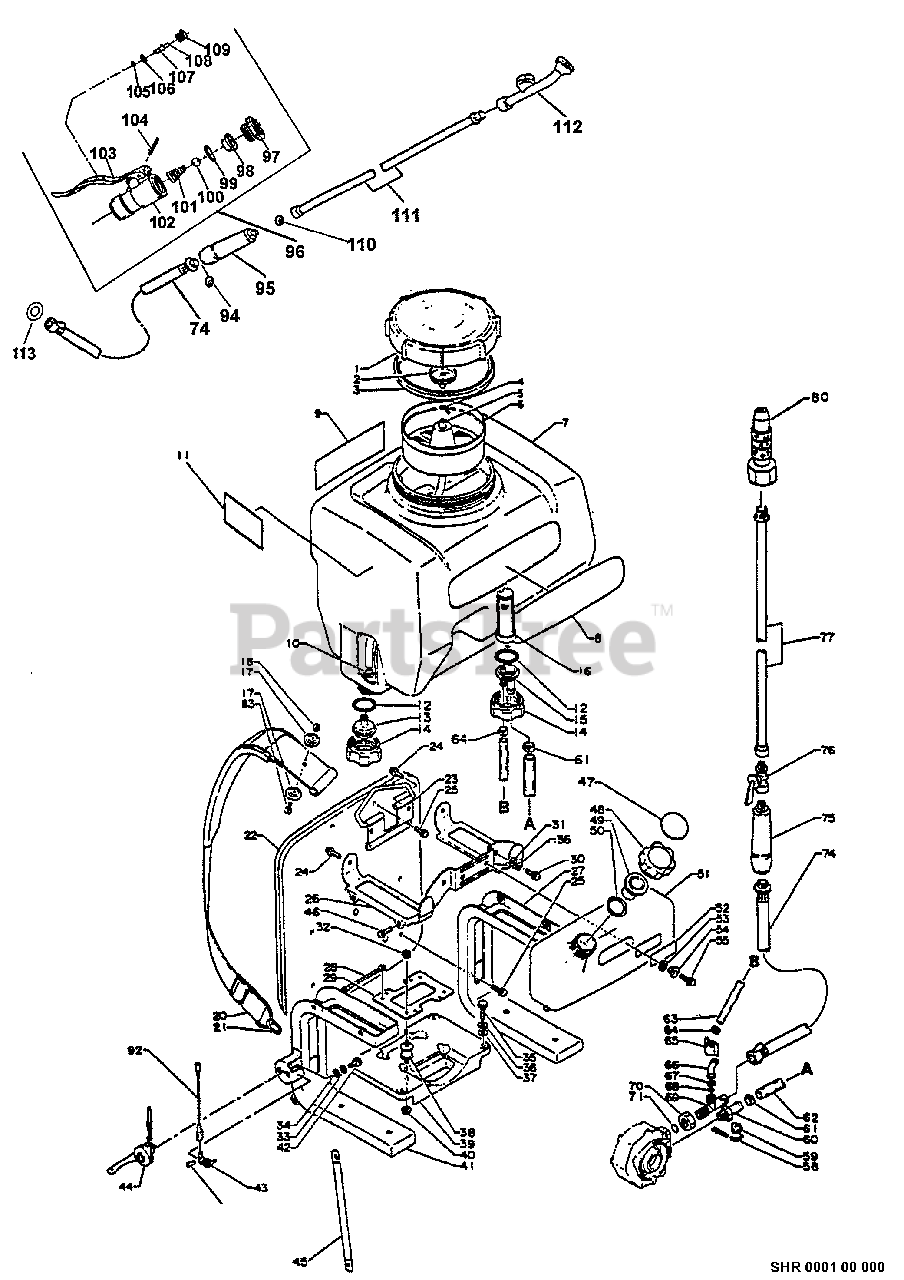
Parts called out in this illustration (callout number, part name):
1	CAP, CHEMICAL TANK
2	CONNECTOR, PIPE
3	GASKET, CHEMICAL TANK
4	CLAMP
5	HOSE, AIR
7	TANK, CHEMICAL
9	LABEL - CAUTION
10	CLAMP
11	LABEL, CAUTION
12	O-RING 28
13	BREATHER
17	WASHER 5.2×22×2.0
18	NUT, LOCK M5
20	BACKPACK STRAP ASSY
21	RING, HARNESS
22	CUSHION, BACKPACK
23	HANGER
24	SCREW 6×10
25	SCREW 5×10
26	BRACKET
27	FRAME, BACKPACK - RIGHT
28	LEAD - GROUND
29	PLATE, CUSHION
30	SCREW 6×10
31	WASHER 6.5×11.5×0.8
32	NUT - 5 -- FLANGE
33	WASHER, SPRING 5
34	WASHER, FLAT 5.5×10×0.8
35	BOLT 6×20
36	WASHER, SPRING 6
37	WASHER 6.5×13×1
39	SUPPORTER
40	NUT - 5 -- FLANGE
41	FRAME, BACKPACK - LEFT
42	BOLT 5×12
43	SWITCH, ON-OFF
44	LEVER, CONTROL
45	BAR
46	SCREW 6×14
47	LABEL - FUEL MIX
49	CAP, VENT
50	GASKET, FUEL CAP
51	TANK, FUEL
52	LABEL - MODEL
54	SPACER
55	SCREW 6×20
58	DRAIN PLUG KIT
60	JOINT, INLET
62	HOSE, INLET
63	HOSE, BYPASS
65	NUT, WING
66	JOINT, BYPASS
67	GASKET, BYPASS NOZZLE
69	FITTING, GREASE
71	O-RING
74	HOSE, SPRAY
75	GRIP
76	VALVE, NOZZLE
77	TUBE, NOZZLE
80	NOZZLE, ADJUSTABLE
83	SCREW 5×14
91	LABEL, ON-OFF
92	LEAD - GROUND
94	GASKET
95	GRIP
96	VALVE ASSY
97	FITTING, GREASE
100	VALVE, BALL 5×16
102	VALVE, NOZZLE
104	PIN, SPRING 3×16
105	FITTING, GREASE
106	E-RING
107	PIN
109	O-RING 3
110	PACKING
111	TUBE, NOZZLE
112	NOZZLE, 2-HEAD
113	GASKET, BYPASS NOZZLE
